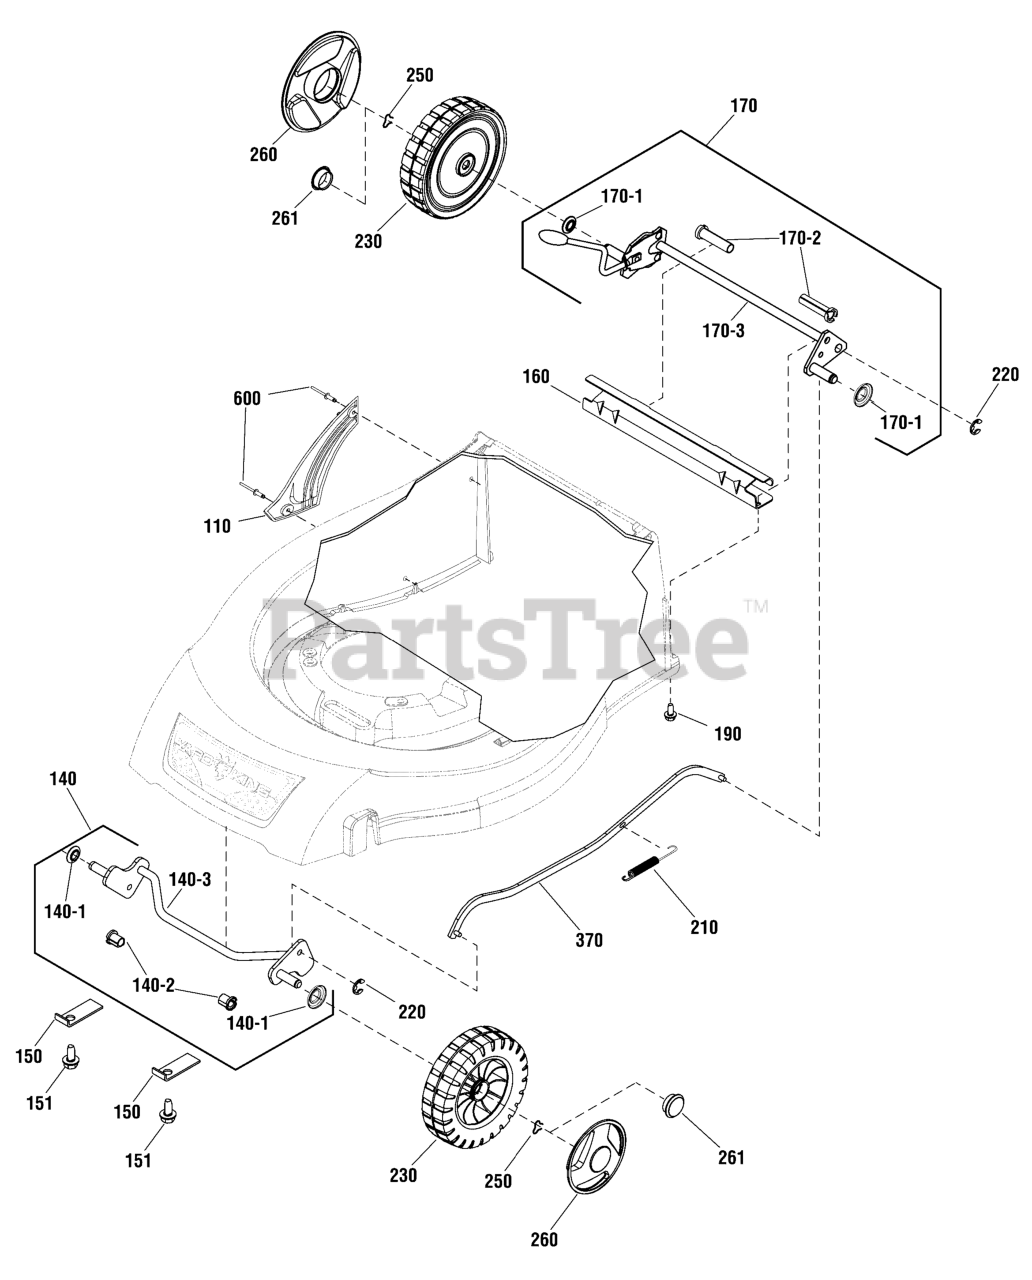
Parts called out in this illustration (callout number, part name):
110	SEGMENT, Height Adjustment
140	AXLE, Front
140-1	DUST SEAL
140-2	BUSH, Front Axle
140-3	AXLE, Front
150	RETAINER, Front Axle
151	SCREW, Front Axle
160	SKIRT, Rear
170	AXLE, Rear
170-1	DUST SEAL
170-2	BUSH, Rear Axle
170-3	AXLE, Rear
190	SCREW, Rear Axle Retainer
210	SPRING, Connecting Link
220	CIRCLIP
230	WHEEL ASSEMBLY, Easy Trak, 8"
250	RETAINER, Wheel
260	HUB CAP
261	HUBCAP, Button
370	LINK, Connecting
600	RIVET
